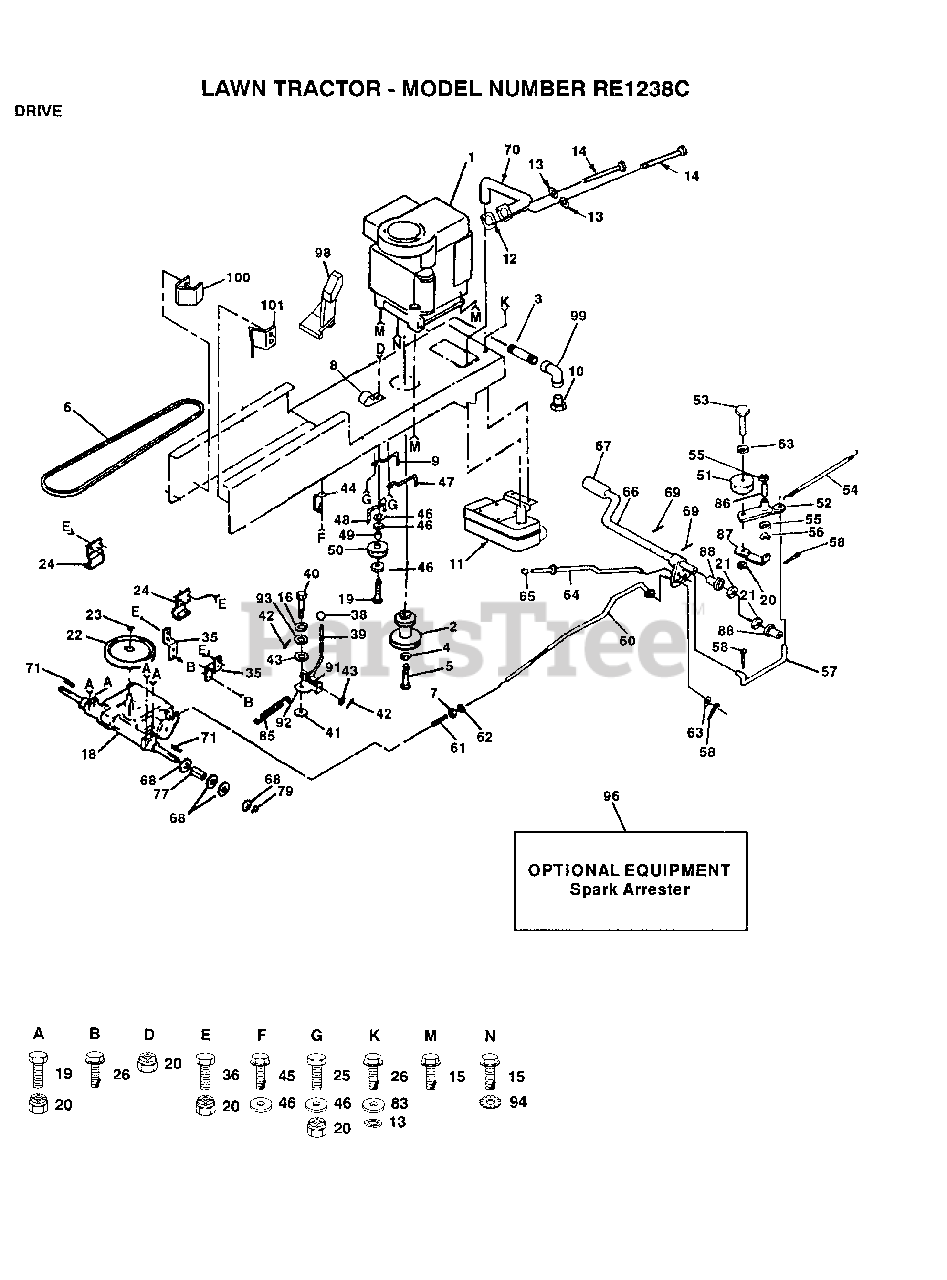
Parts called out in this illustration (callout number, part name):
3	PIPE NIPPLE
4	LOCKWASHER
5	BOLT
6	BELT-V.90.0.GD.DR
7	NUT
8	CLIP T
9	KEEPER.BELT.ENG.L
11	MUFFLER EUROPE
13	LOCKWASHER
14	SCREW LT
15	SCREW
16	LOCKWASHER
19	BOLT
21	WASHER LT
22	PULLEY TRANS
24	BRACKET LT
25	BOLT
26	SCREW
35	STRAP TORQUE
38	CONTROL KNOB LT
39	ROD SHIFTER
41	WASH-SHFT PLT LT
42	PIN COTTER 1/8
43	WASHER
45	SCREW
46	WASHER
47	GUIDE BLT DR MWR
48	BELT KEEPER LT
49	SPACER T
50	PULLEY.IDLER.FLAT
52	ARM IDLER
54	"SPRING, RETURN LT"
55	WASHER LT
56	KLIP RING
57	"LINK, CLUTCH T"
58	COTTER PIN
61	SPRING ROD LT
62	NUT
63	WASHER
67	PEDAL COVER T
68	WASHER
70	PIPE EXHAUST
71	SQUARE KEY
77	SPACER LT
79	E-RING LT
83	WASHER
86	"LY, BEARING"
87	RETAIN BELT
88	NYLON BEARING
91	SPRING LT
92	PLATE SHIFT LT
93	WASHER LT
94	LOCKWASHER
96	SPARK ARREST KIT
99	ELBOW
100	"KEEPER,BELT LH T"
101	"KEEPER,BELT RH T"
